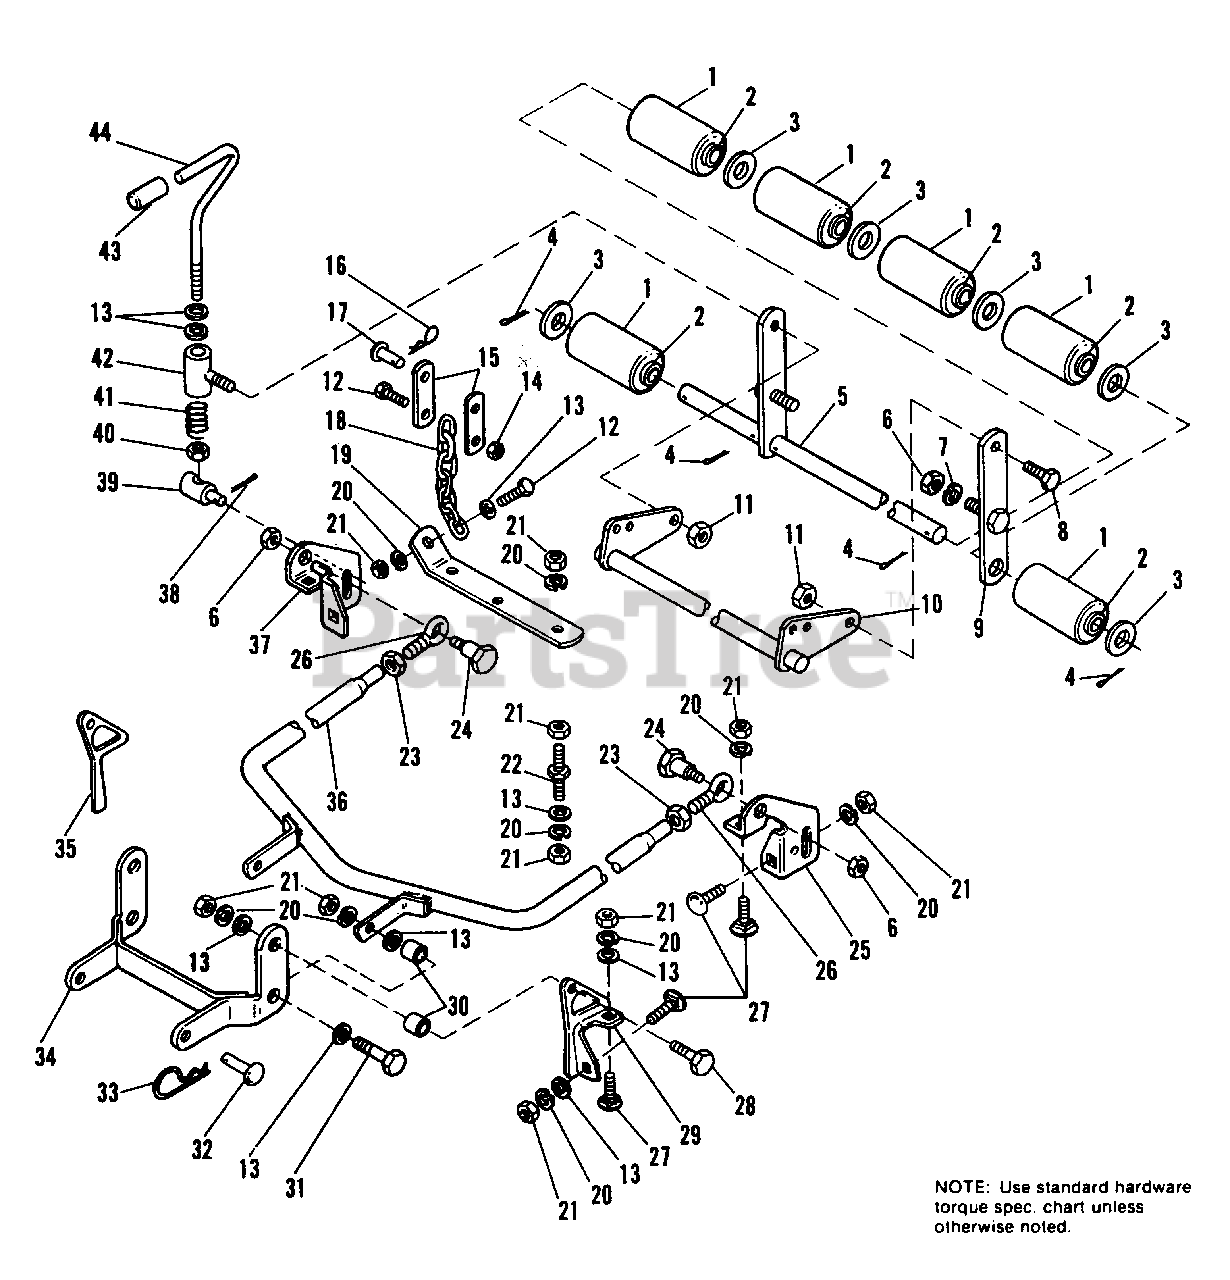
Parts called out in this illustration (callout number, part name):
1	ROLLER ASSY., W/Bushing
4	PIN, Cotter, 3/16 x 1
5	ROLLER BAR & SHAFT ASSY.
6	LOCKNUT, Hex, 3/8-16
7	WASHER, Plain, 5/16
8	CAPSCREW, Hex Hd., 3/8-16 x 1
9	BAR ASSY., Roller
10	LEVER ASSY., Rear
11	LOCKNUT, Hex, Jam, 3/8-16
12	CAPSCREW, Hex Hd., 5/16-18 x 1
13	WASHER, Plain, 3/8
14	LOCKNUT, Hex, 5/16-18
15	LINK, Mower Lift
16	CLIP, Hair Pin
18	CHAIN
19	BAR, Lift
20	LOCKWASHER, 3/8
21	NUT, Hex, Full, 3/8-16
23	LOCKNUT, Hex, Jam, 1/2-20
24	BOLT, Shoulder
25	BRACKET, Rear, L.H.
27	BOLT, Carriage, 3/8-16 x 3/4
28	CAPSCREW, Hex Hd., 3/8-16 x 1
29	BRACKET, Front, L.H.
31	CAPSCREW, Hex Hd., 3/8-16 x 1-1/4
33	CLIP, Safety Pin
34	ARM ASSY., Rocker
35	BRACKET, Front, R.H.
36	BAIL ASSY.
37	BRACKET, Rear, R.H.
38	PIN, Cotter, 3/32 x 3/4
40	LOCKNUT, Hex, Jam, 3/8-16
42	SOCKET ASSY., Crank
43	GRIP, Handle
44	SCREW ASSY., Adjusting
